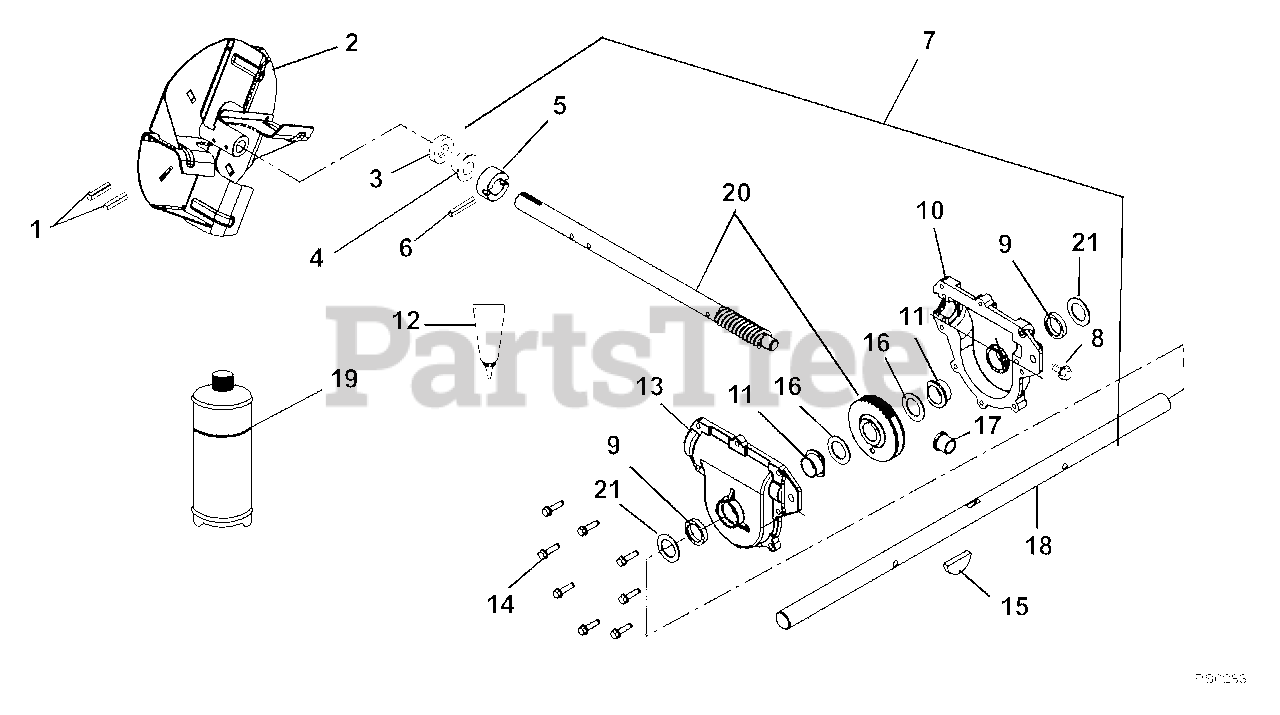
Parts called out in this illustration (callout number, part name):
1	PIN-ROLL .250X1.75
2	IMPELLER-14" 4 BLADE
3	SEAL-OIL .875X1.375X.25 RBR OD
4	BSHG-FLG .876 X 1.500 X .750
5	THRUST COLLAR, .875" ID
6	PIN-GRV .250X1.50 TP E
7	GEARCASE ASS'Y - 26" ALUMINUM
7	GEAR CASE, ALUM-LARGE 28"
7	GEAR CASE, ALUM-LARGE 32"
8	SCR-TAP .38-16X.75 ROLOK YZ WX
9	SEAL-OIL 1.000X1.375X.250
10	GEARCASE, ALUMINUM, LH
11	BSHG-FLG 1.003X1.5X.625
12	LOCTITE GASKET 518--850CC CRTG
13	GEARCASE, ALUMINUM, RH
14	@SCR-TAP .25-20X1.00 HWH TR YZ
15	KEY-WDRF .25X.875X.375 SAE A
16	WSHR-HRD-THRS 1.007X1.542X.062
17	BSHG-FLG .629 X 1.000 X .750
18	SHAFT, RAKE-26"
18	SHAFT, RAKE-32"
18	SHAFT, RAKE-28"
19	ARIENS 16 OZ.BOTTLE OF L2 LUBE
20	ASSY, WORM SHAFT & GEAR
21	WSHR-FL-STL 1.010X1.505X.062YZ
